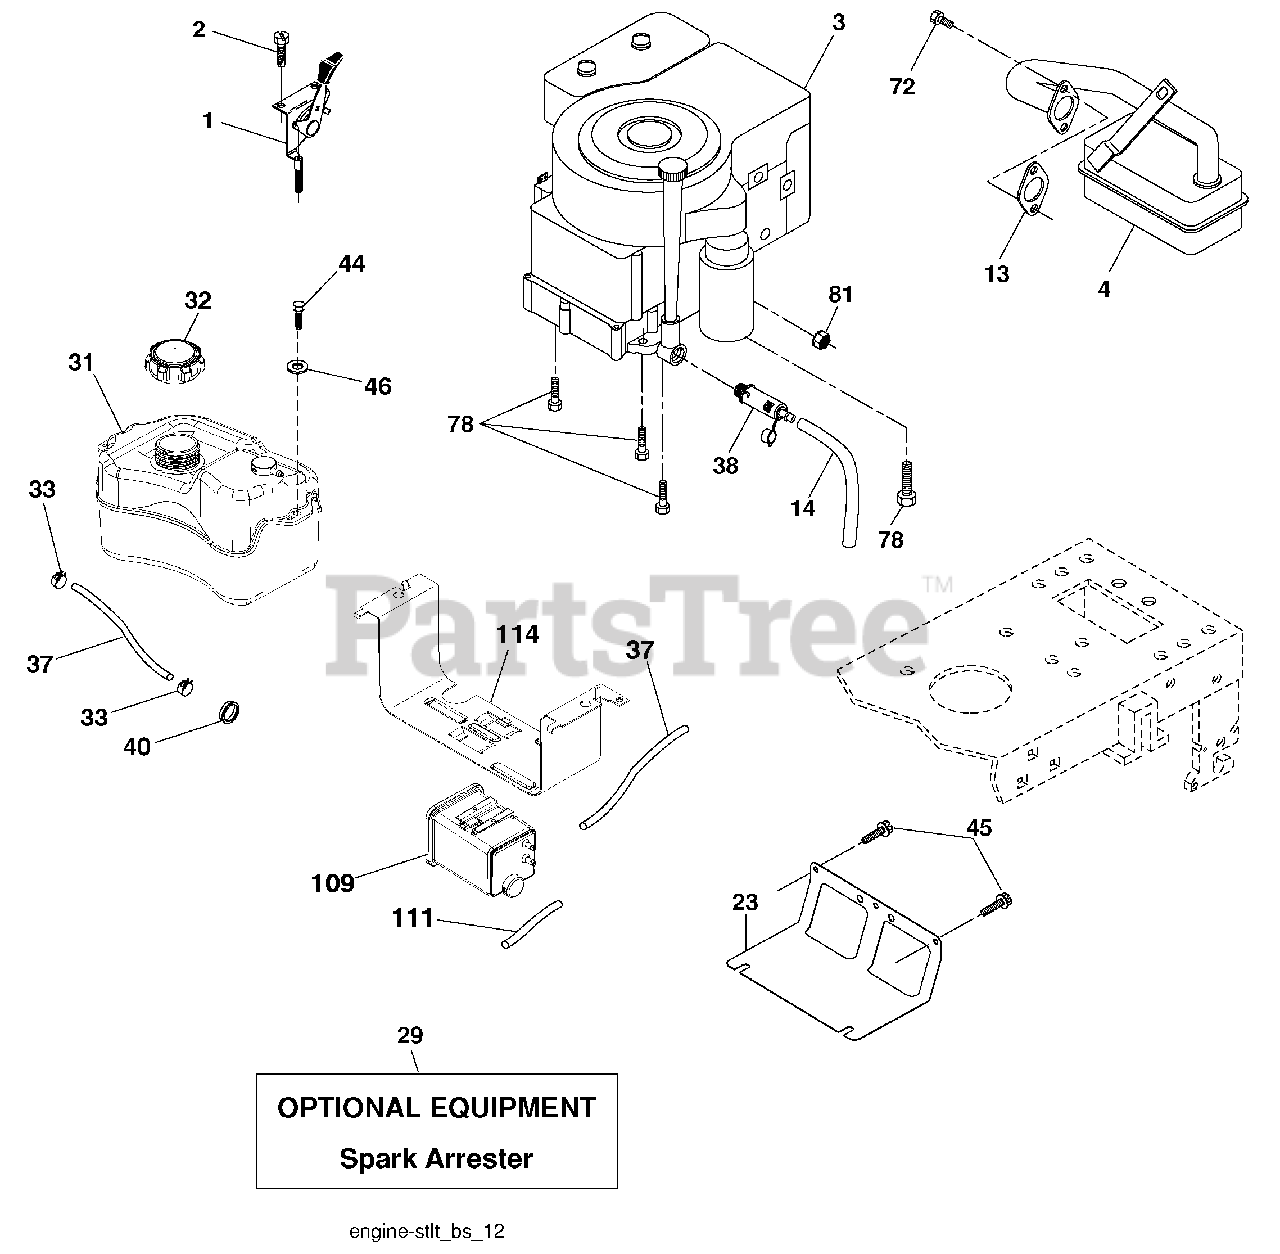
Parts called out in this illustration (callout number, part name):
1	Control Th/ch Flag
2	Screw Hex Thd Cut 1/4-20 x 1/2
4	Muffler Exhaust B&S
13	Gasket Eng 1 313 Id Tin Plated
14	Tube Drain Oil Easy
23	Shield BRN/DBR Guard
29	Kit Spark Arrestor (Flat Scrn)
31	Tank Fuel Front Asm
32	Cap Asm Fuel
33	Clamp Hose
37	Line Fuel
38	Plug Drain Oil
40	Bushing
44	Screw Thdrol 1/4-20 x 3/4
45	Screw Hex Wsh Thdrol 3/8-16
46	Washer 9/32 x 7/8 x 16 Ga.
72	Screw Socket Head 5/16-18 x 3/4
78	Screw 3/8-16 x 1-1/4
81	Nut Keps Hex 1/4-20 unc
109	Canister Carbon Filter Asm.
111	Purge Line
114	Cradle Canister Carbon
